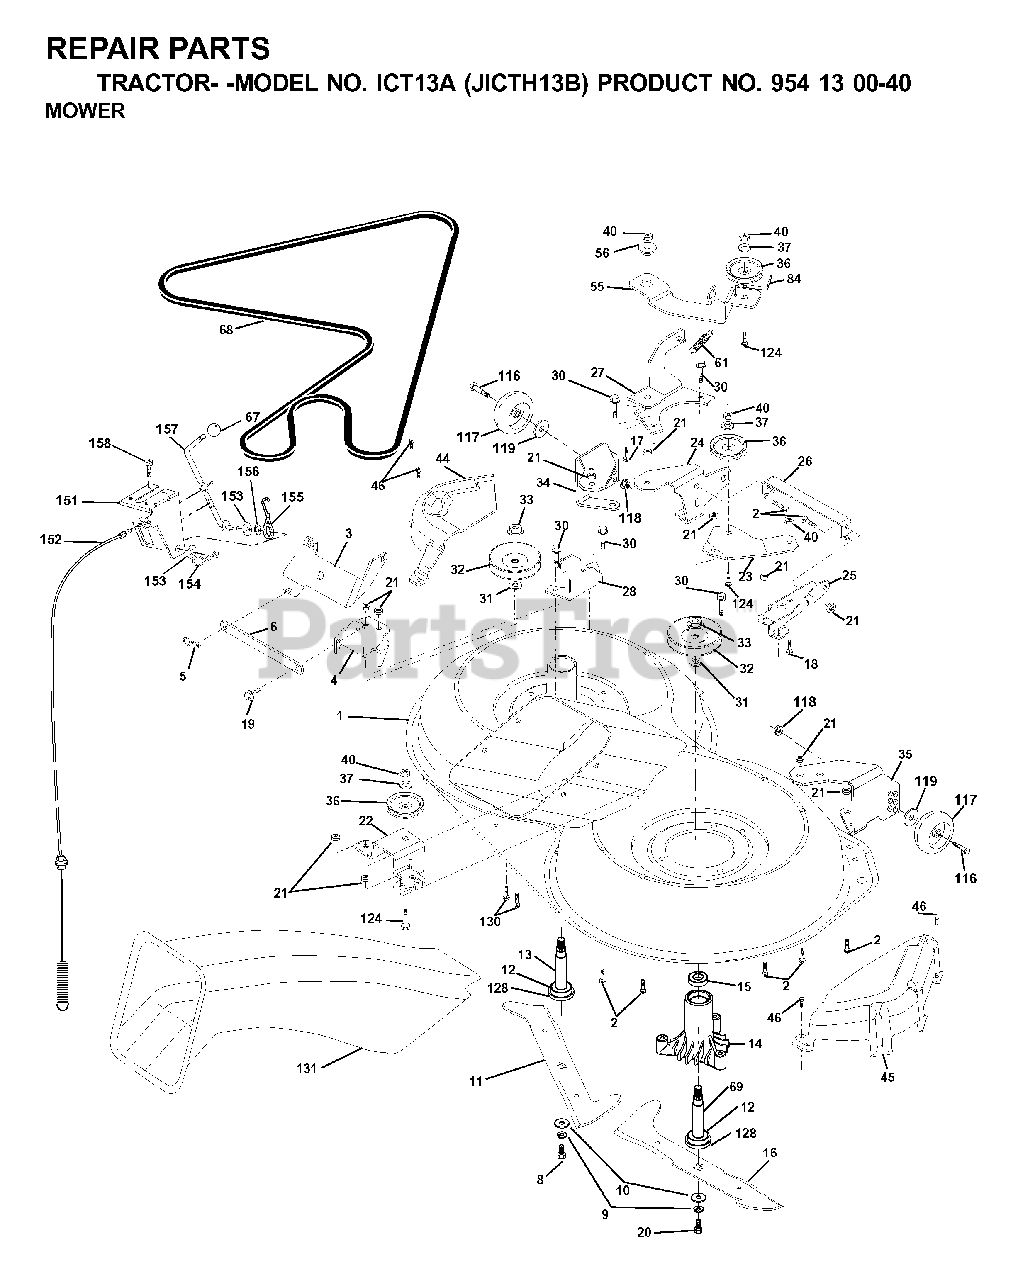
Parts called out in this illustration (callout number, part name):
1	MOWER HOUSING, DECK
3	BRACKET
5	RETAINER-SPRNG RB
6	BAR SWAY
8	BLADE BOLT
9	LOCKWASHER
10	WASHER.BLADE
11	BLADE
12	BEARING
13	SHAFT ASM VENT
14	HSG MANDREL
16	BLADE
17	BOLT.3/8-14X1.25
19	BOLT SHD 5/16-18
21	LOCKNUT
24	BRACKET
25	BRACKET
26	BRACE
28	BRACKET
30	SCREW THDROL ROLLING WASHER HD
31	WASHER
32	PULLEY, MANDREL
33	NUT
36	PULLEY.IDLER.4.25
40	LOCKNUT
45	COVER
46	SCREW.1/4-20X5/8
55	ARM IDLER
56	SPACER RETAINER
61	SPRING.TENSION.BELT
67	KNOB T (3/8 HOLE)
69	SHAFT.ASM.W/LWR.BRG.RH.THREAD
84	KEEPER, BELT IDLER
116	BOLT, SHOULDER
117	WHEEL GAGE DONUT
118	LOCKNUT
119	WASHER
124	BOLT.3/8-16X1.50
128	WASHER FELT
131	CHUTE BAGGER
151	BRACKET, CLUTCH CABLE
153	WASHER FLAT 3/8"
154	SPRING RETAINER
155	SPRING RETENTION LEVER
156	SPACER CLUTCH CABLE
157	ROD CLUTCH CABLE 3/8"
158	SCREW LT
8721	BOLT
